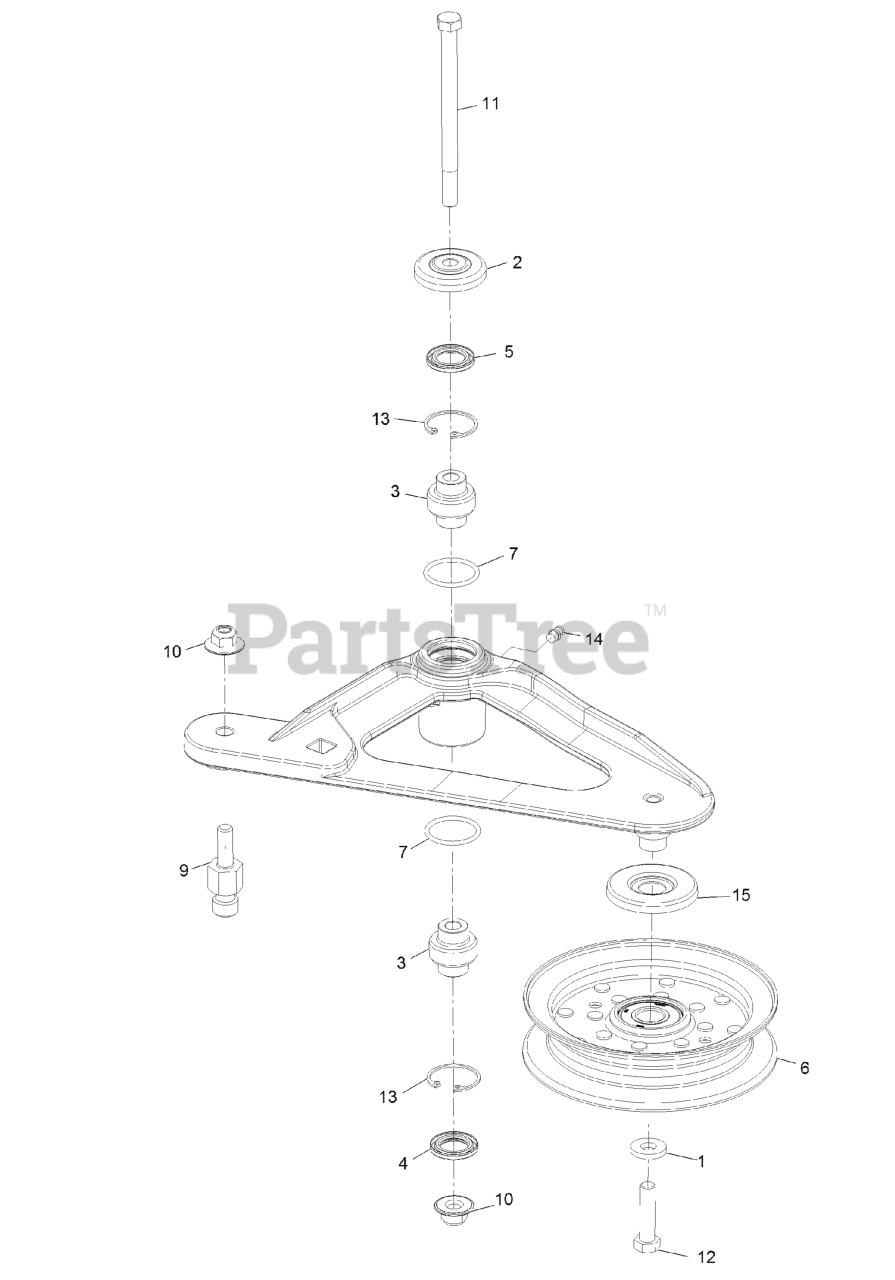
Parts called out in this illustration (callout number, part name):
2	GUARD-TOP
3	BEARING-SPHERICAL
4	SEAL-LIP, DOUBLE
5	SEAL-LIP, SINGLE
6	IDLER-PULLEY, FLAT
9	PIN-SPRING, ANCHOR
10	Nut-Nyloc 3/8-16 Flg
11	SCREW-SHOULDER, HH
12	SCREW-HH
13	RING-SNAP
14	FITTING-GREASE
15	SHIELD-GUARD, DUST
